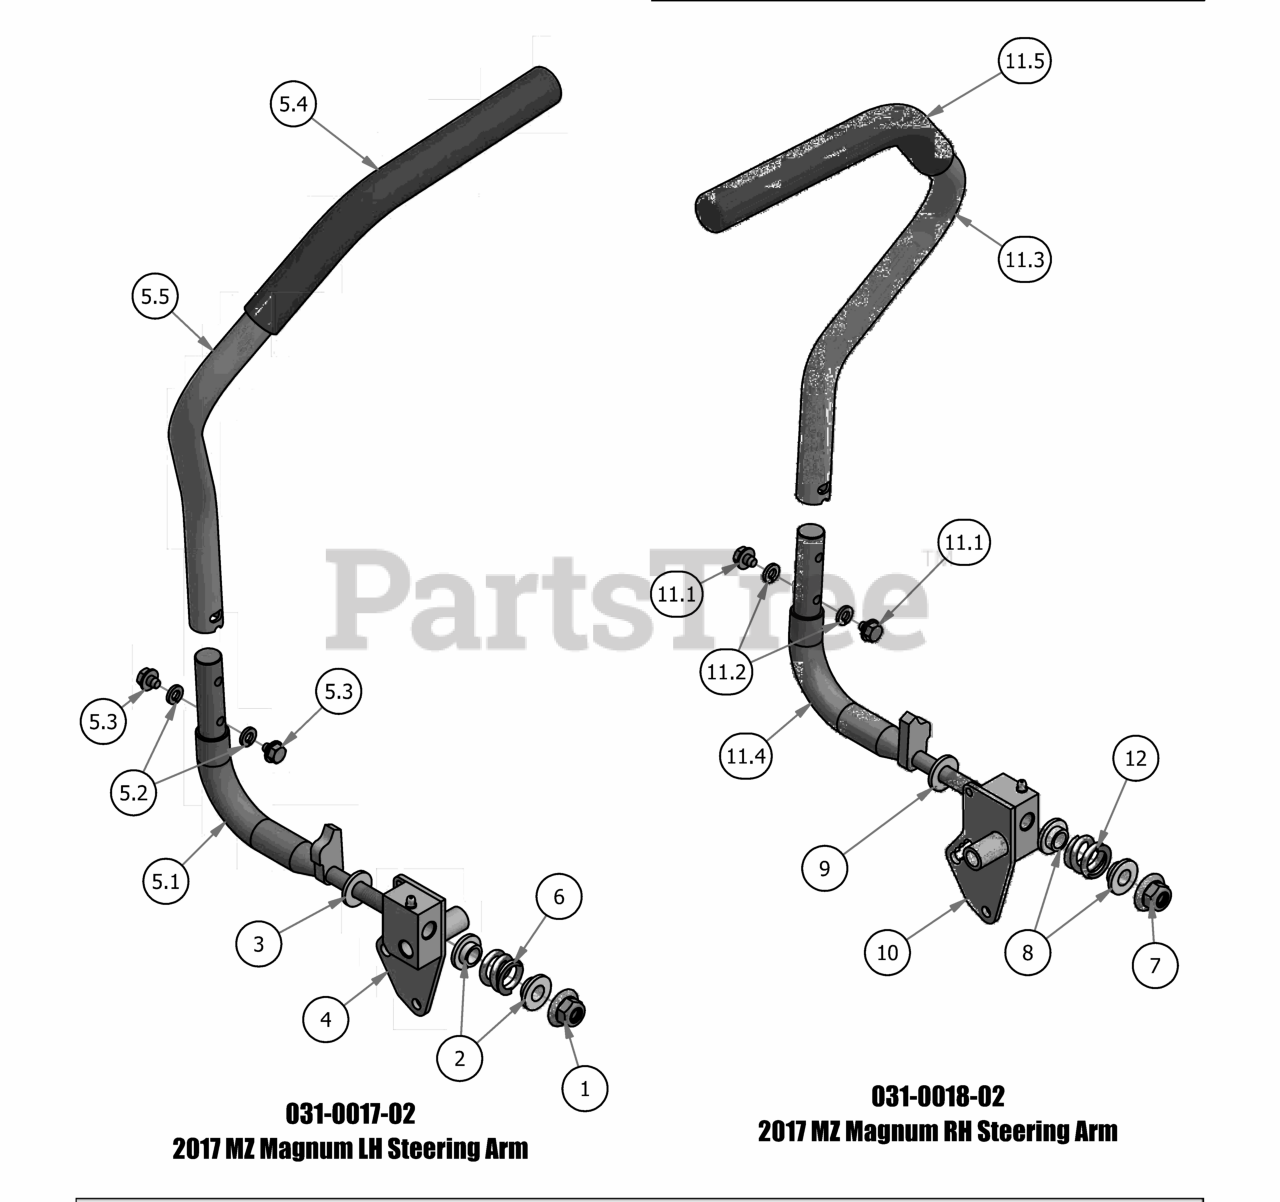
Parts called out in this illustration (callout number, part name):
1	1/2-13 Nylon Flange Nut
2	.515 ID Nylon Shoulder Washer
3	.505 Nylon Spacer
4	2017 Drive Lever Housing - Left
5	ZT Steering Arm-Left
5.1	Stering Arm Elbow (Left)
5.2	5/16" Lock Washer
5.3	5/16-18 1/2 HWH Bolt-Steering
5.4	Rubber Grip
5.5	ZT Direction Steering Arm (Left)
6	Drive Lever Spring
7	1/2-13 Nylon Flange Nut
8	.515 ID Nylon Shoulder Washer
9	.505 Nylon Spacer
10	2017 Drive Lever Housing - Right
11	ZT Steering Arm-Right
11.1	5/16-18 1/2 HWH Bolt-Steering
11.2	5/16" Lock Washer
11.3	ZT Direction Steering Arm (Right)
11.4	Stering Arm Elbow (Right)
11.5	Rubber Grip
12	Drive Lever Spring
